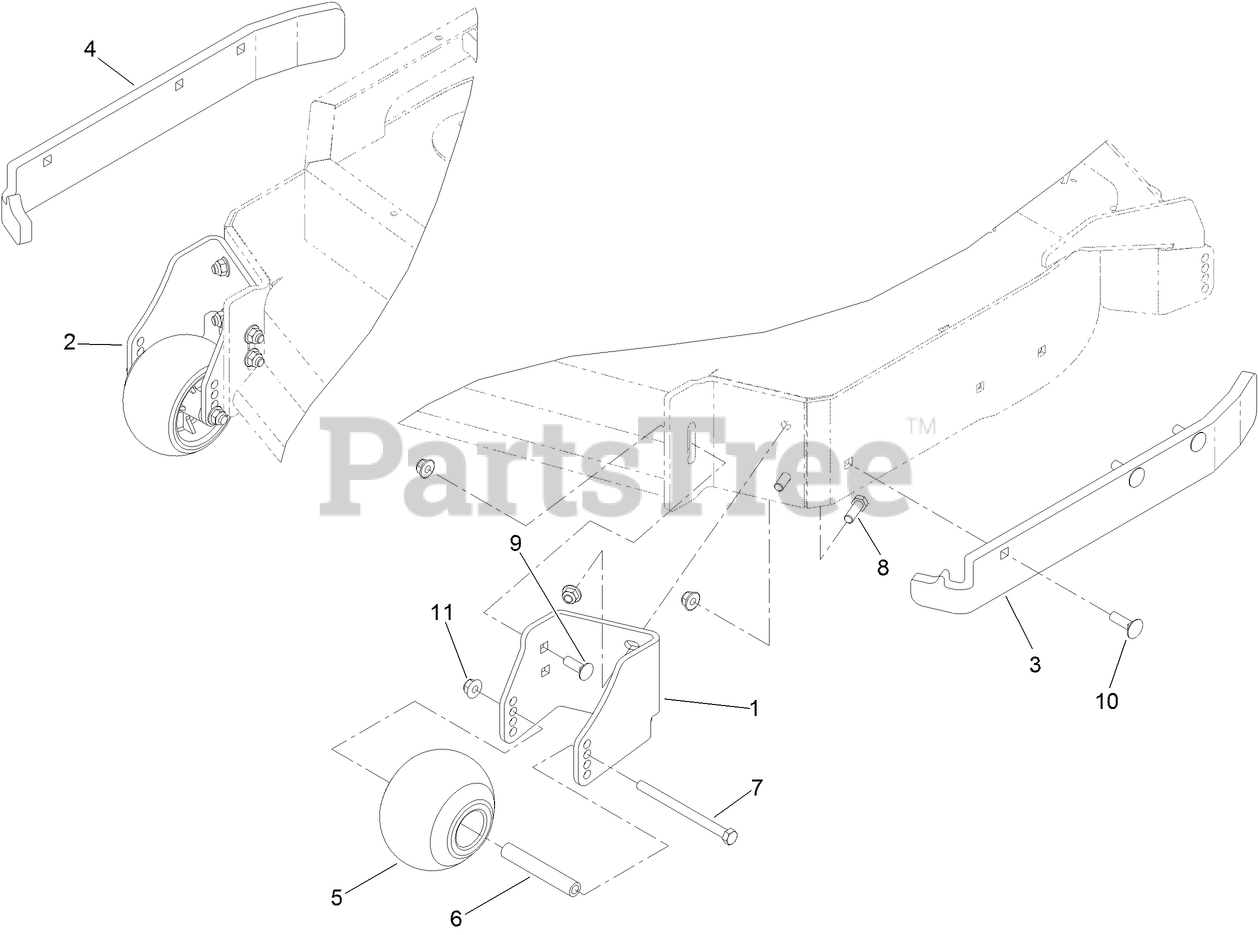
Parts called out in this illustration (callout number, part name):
1	BRACKET-SCALP, ANTI (LH)
2	BRACKET-SCALP, ANTI (RH)
3	BUMPER-DECK, LH
4	BUMPER-DECK, RH
5	ROLLER-ANTI-SCALP
6	TUBE-SPACER
7	SCREW-HH
8	SCREW-HH
9	SCREW-CARR
10	BOLT-CARR
11	NUT-HF, NI
